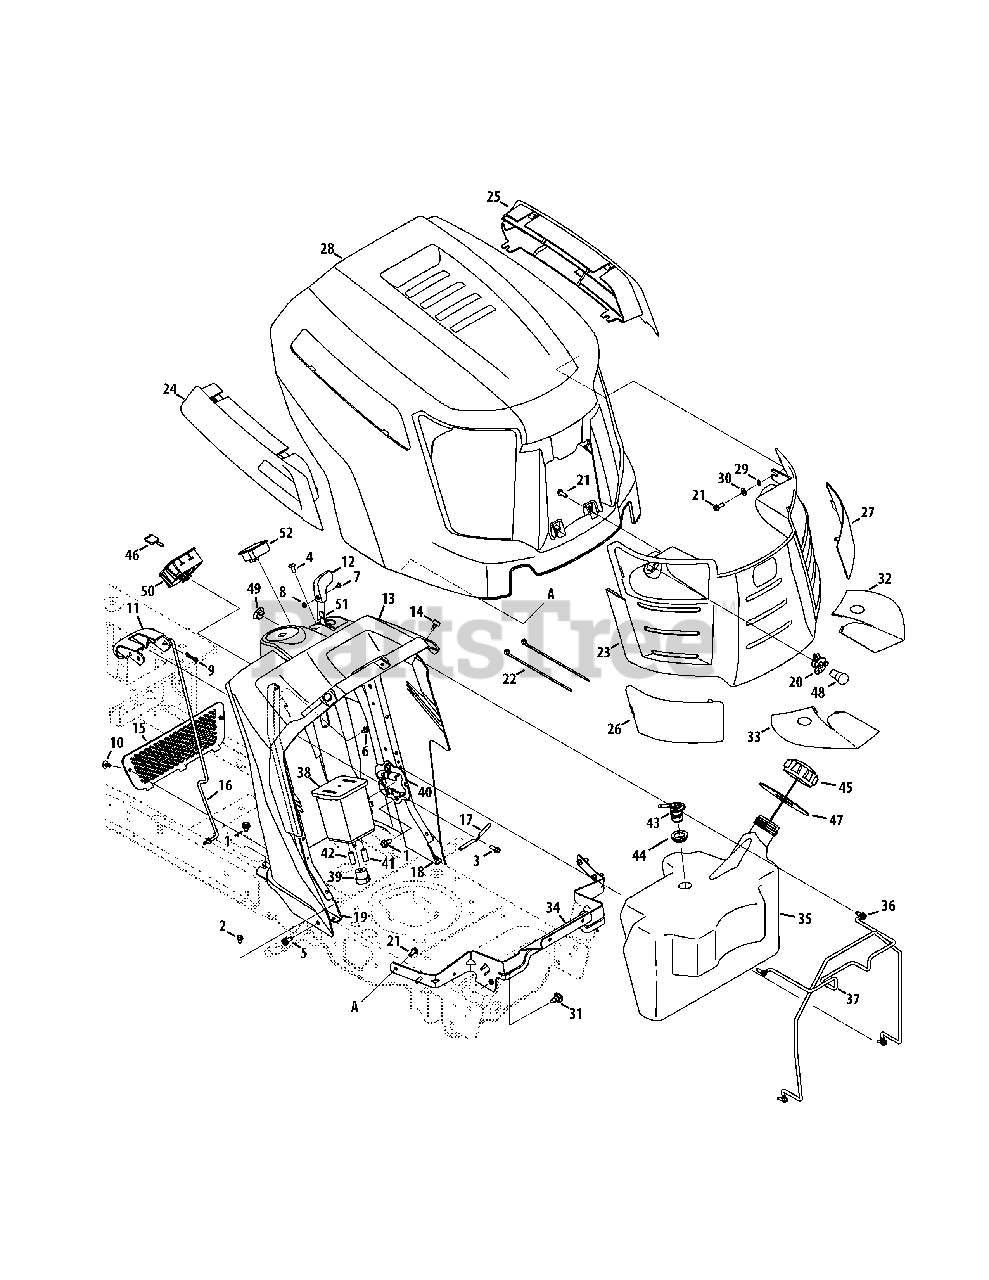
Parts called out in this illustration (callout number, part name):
1	Screw, Self-tapping, 5/16-18, .750
2	Screw, Self-tapping, 1/4-20, 0.500
3	Screw, HL, 1/4-15, 0.750
4	Screw, Ab, 1/4-14, 0.625,
5	Screw, Self-tapping, 5/16-18, 0.750,
6	Screw, Self-tapping, 1/4-20 x .625
7	Screw, Mach, #8-32, 0.375
8	Nut, Hex, #8-32
9	Pin, Cotter, Bow-Tie 72
10	Clip, Ratchet, .250 Dia
11	Lever, Dash, Cruise/Brake
12	Knob, Throttle
13	Dash Panel, A-Style, Man PTO
14	Bumper, .62 Dia X .3
16	Rod, Control, Latch Cub
17	Rod, Lever, Bent
18	Support, Dash, Plate LH
19	Support, Dash, Plate RH
20	Socket, Lamp
21	Screw, 1/4 Dia, .750
22	Tie, Cable, Push Mount 7.5 Lg
23	Grille Ass’y (Incl. 26, 27, 32 & 33)
24	Scoop, Hood, RH A-Style
25	Scoop, Hood, LH A-Style
26	Lens, Hood, RH A-Style
27	Lens, Hood, LH A-Style
28	Hood, A-Style
29	Washer, Lock, 1/4, External
30	Washer, Flat, .271, .630, .065
31	Screw, Shoulder, .43x.29, 5/16-18
32	Reflector, Cub A Style, LH
33	Reflector, Cub A Style, RH
34	Bracket, Pivot, Hood A-Style
35	Tank, Fuel, 3.75 Gal.
35	Tank, Fuel, 3.30 Gal. (CA)
36	Screw, Self-tapping, 1/4-20, .625
36	Screw, Self-tapping, 1/4-20, .75 (CA)
37	Rod, Support, Fuel Tank
38	Cnstr, Carbon, 5 Gallon (CA)
39	Filter, Vent, Canister (CA)
40	Bracket, Adapter, Canister (CA)
41	Hose, Fuel, Low Perm, 3/16 Wht (CA)
42	Hose, Fuel, Low Perm, 7/32 Yel (CA)
43	Valve, Rollover Grommet (CA)
44	Grommet, Rubber, 23.0 ID (CA)
45	Cap, Fuel
45	Cap, Fuel (CA)
46	Key, Ignition
47	Gasket, Fuel Tank
48	Lamp, 12v
49	Plug, Choke
50	Module Switch, Ignition
51	Cable, Throttle/Choke, 28"
52	Meter, Indicator
